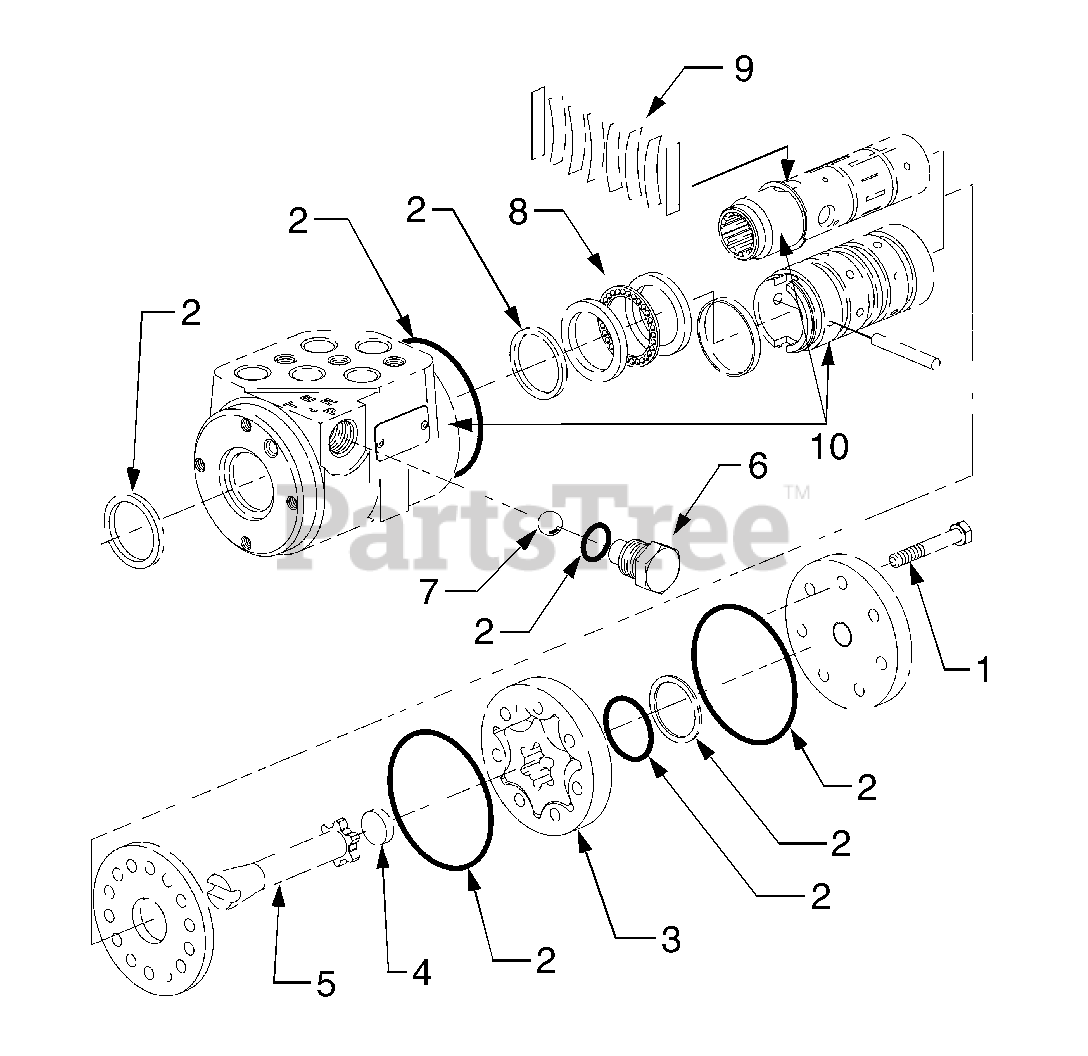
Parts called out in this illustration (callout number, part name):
1	Screw, Hex Cap, 1.57" Lg.
2	Seal Kit
3	Gerotor Assembly
4	Spacer, .240 Lg.
6	Plug, Manual Check
7	Ball, Manual Check
9	Spring Kit, Centering
10	Spool, Sleeve and Housing
